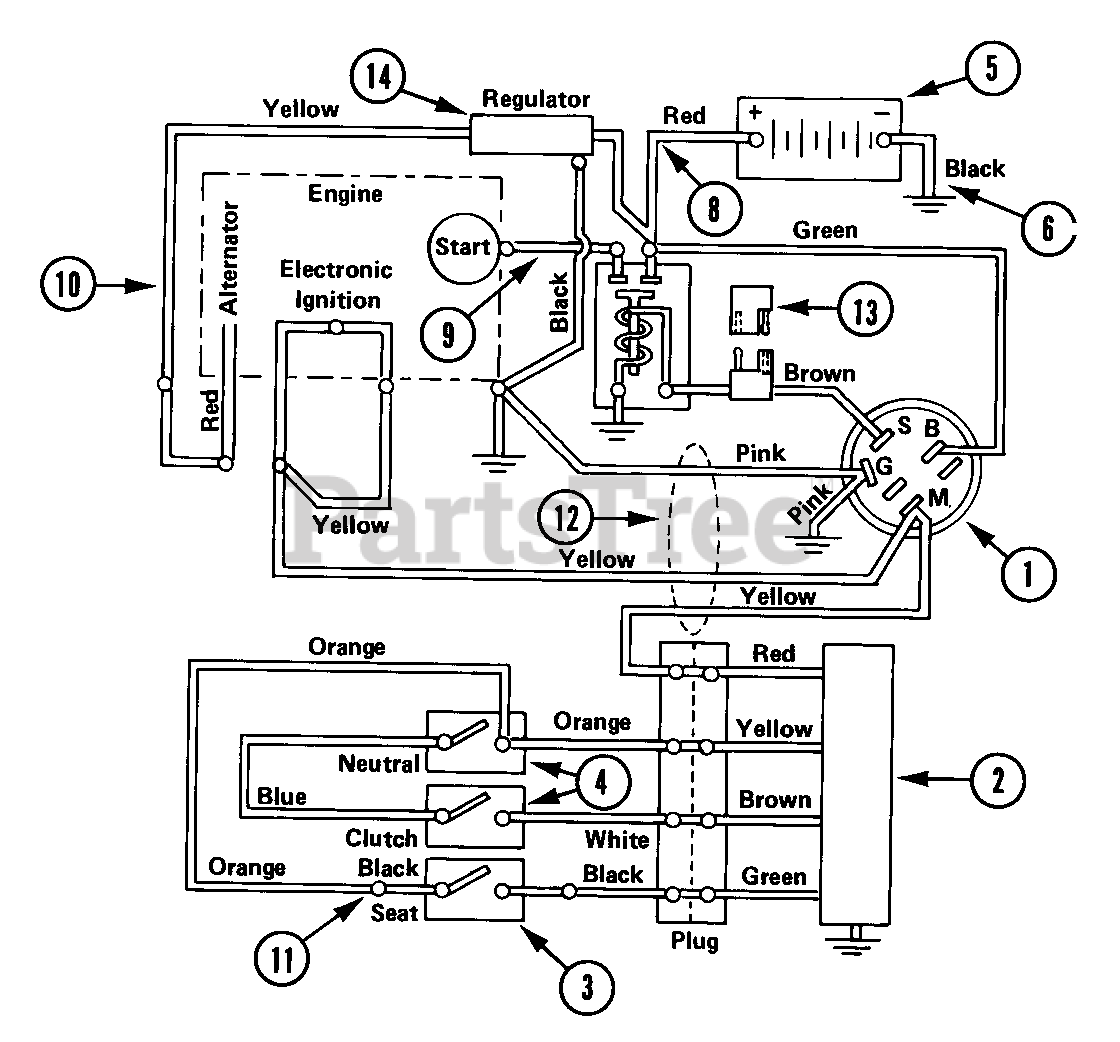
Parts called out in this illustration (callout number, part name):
1	IGNITION SWITCH ASSEMBLY
2	MODULE
3	SAFETY SWITCH
3	SEAT WITH SWITCH REPLACEMENT P
3	SWITCH SEAT
4	SWITCH INTERLOCK
5	BATTERY
6	GROUND CABLE .25X13.00X.31
9	START CABLE 22"
10	CHARGING WIRE
11	ADAPTER - SEAT SWITCH
12	WIRE HARNESS
13	DIODE & HOUSING
14	REGULATOR
